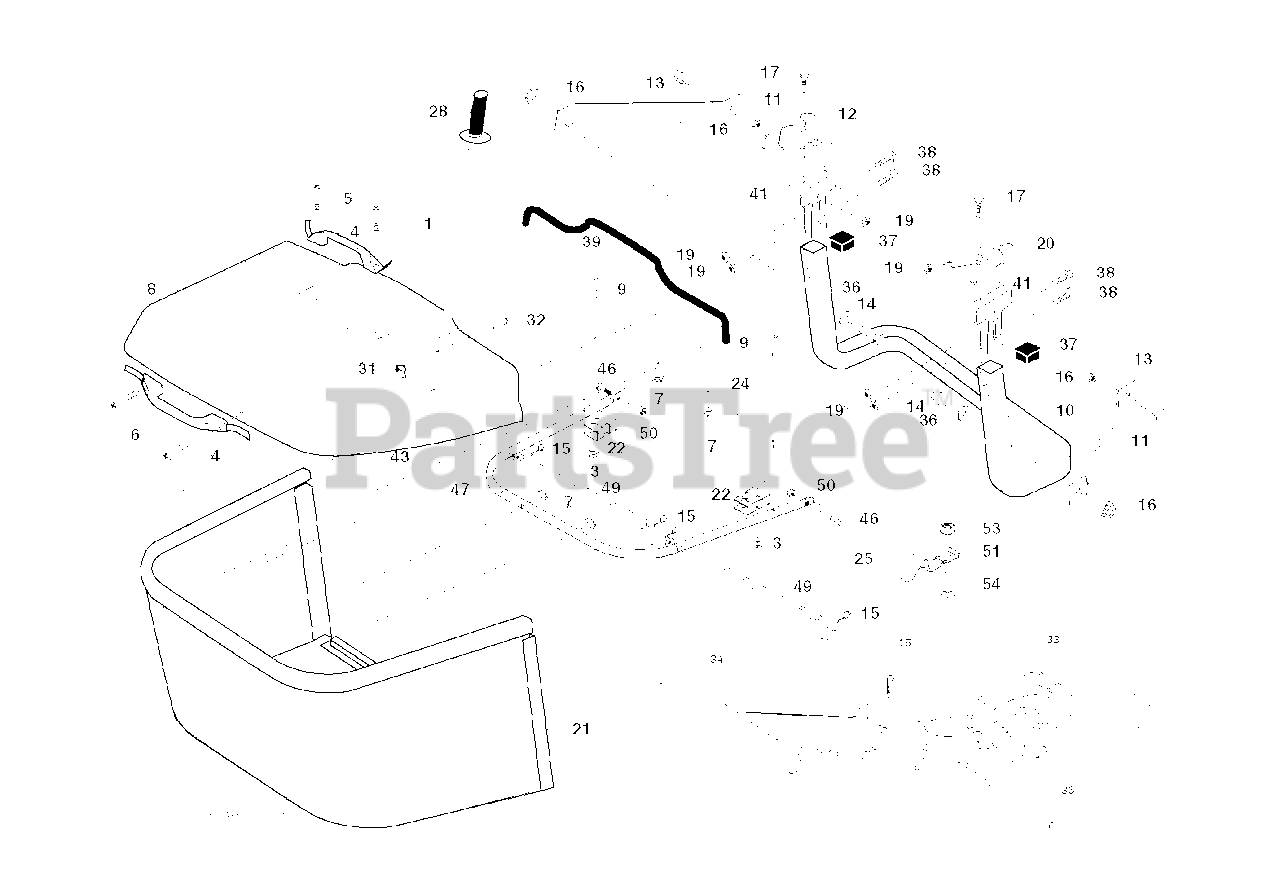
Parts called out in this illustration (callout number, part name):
1	TUBE.PNT.HDL.BAGGER.
3	NUT T
5	SCREW.PAN.HEAD
11	BRACKET
14	BOLT-HEX EAK
15	RETAINER-SPRNG RB
16	NUT LOCK FLG 3/8-16 UNC
17	BOLT
19	NUT LOCK HEX FLANGE 5/16-18
20	BRKT.PIVOT.RH.CRD
21	BAGGER.ASM.CRD.2007
22	BRACKET
24	TUBE
28	GRIP.HANDLE.BLACK
31	RETAINER CLIP
32	RIVET,DRILLED
33	MULCHING.PLUG.1078.CRD.NON-TEX
35	PIN
38	BOLT.5/16-18X2.5
39	SEAL.BAGGER.CRD
41	BRKT, BAGGER
43	PLUG, TUBING END
46	BOLT.CARRIAGE.5/16-18
50	NUT.71038.31-18.HEX.NYLOCK
53	NUT
54	BOLT
